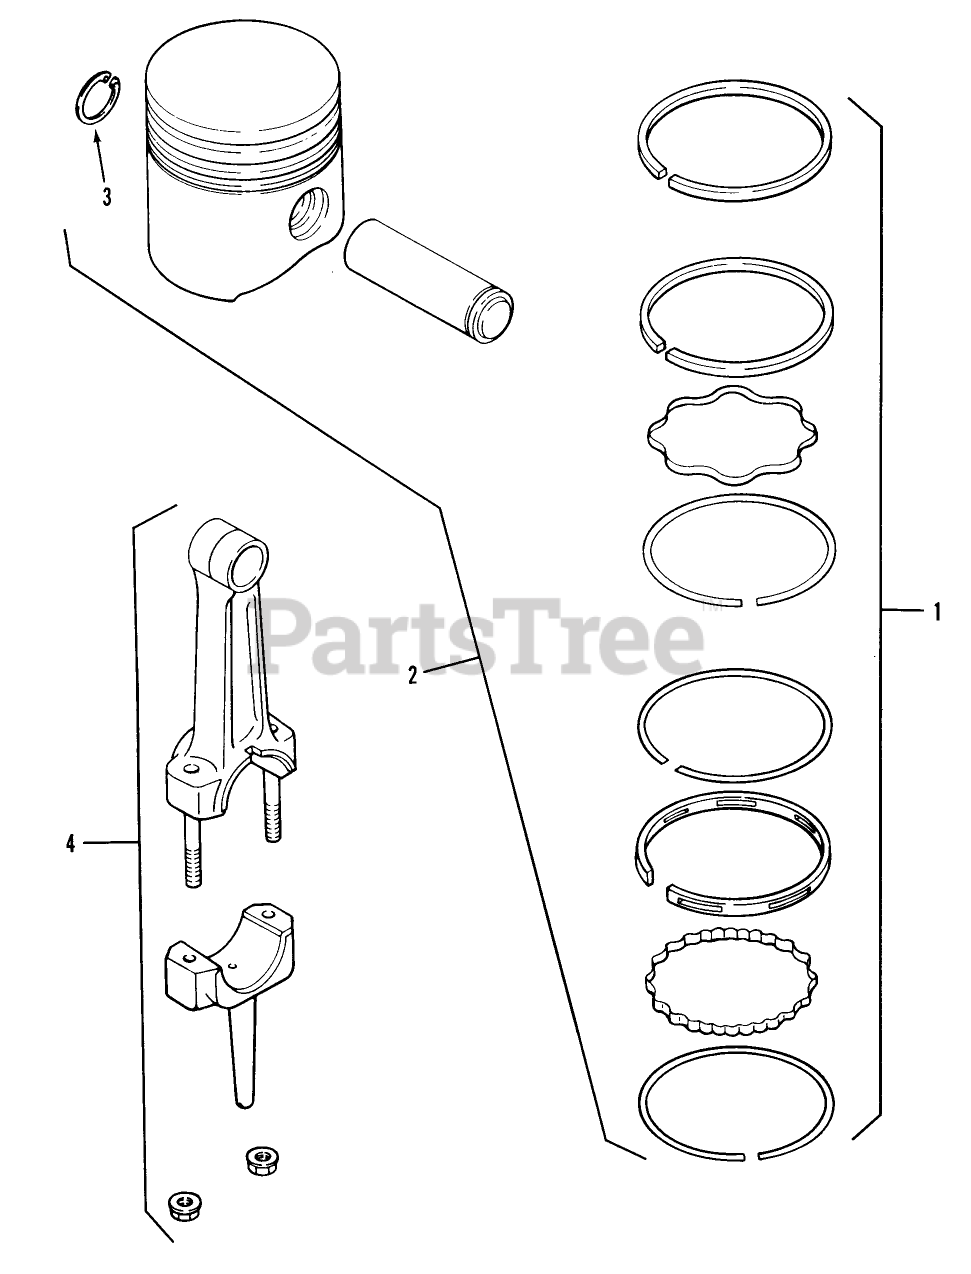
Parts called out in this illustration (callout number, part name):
1	Ring set-Std. 003 (Svc.)
2	Piston w/Ring Set Std. 310
3	Retainer-Piston Pin
4	Connecting Rod Std. 310
